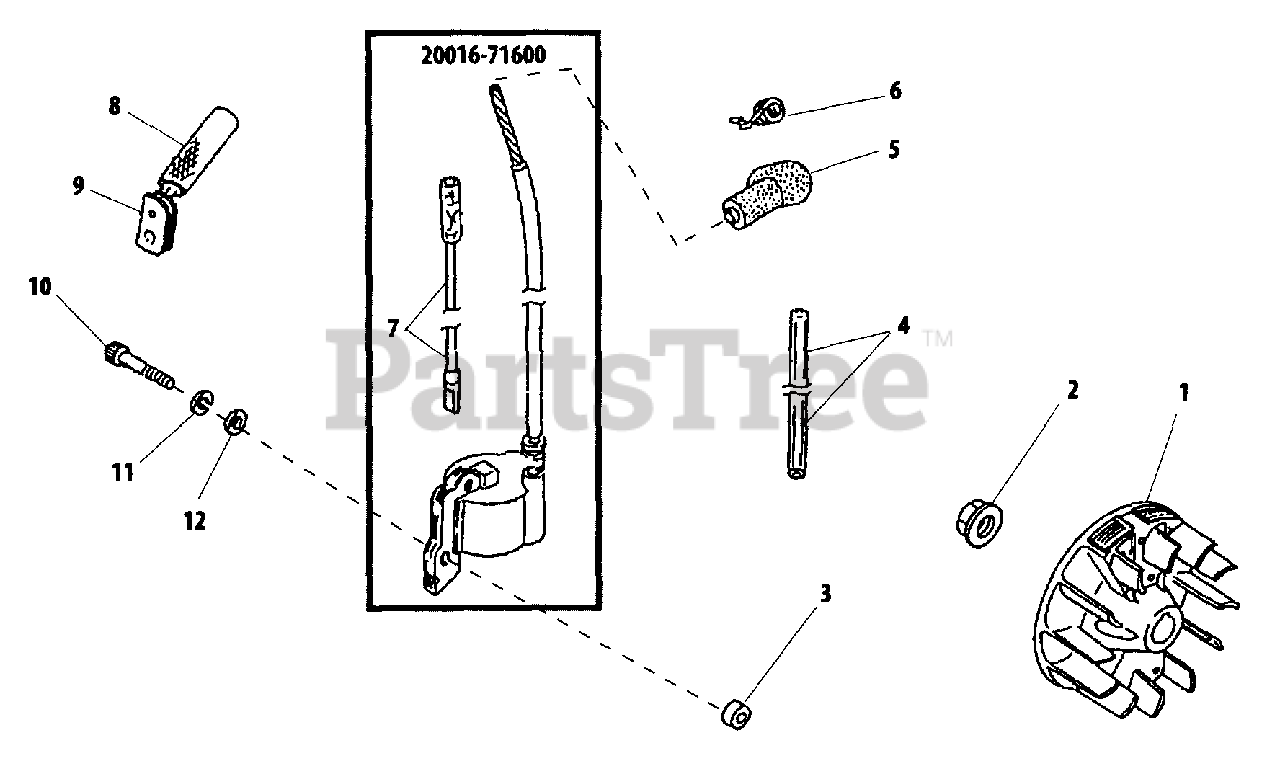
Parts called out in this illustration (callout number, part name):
1	FLYWHEEL
2	NUT - 8
3	INSULATOR
4	TUBE
5	CAP, SPARK PLUG
6	TERMINAL, SPARK PLUG CAP
7	LEAD - IGNITION
8	TUBE
9	GROMMET
10	SCREW - 4X26
11	LOCKWASHER - 4
12	WASHER - 4
20016-71600	IGNITION COIL ASSY
